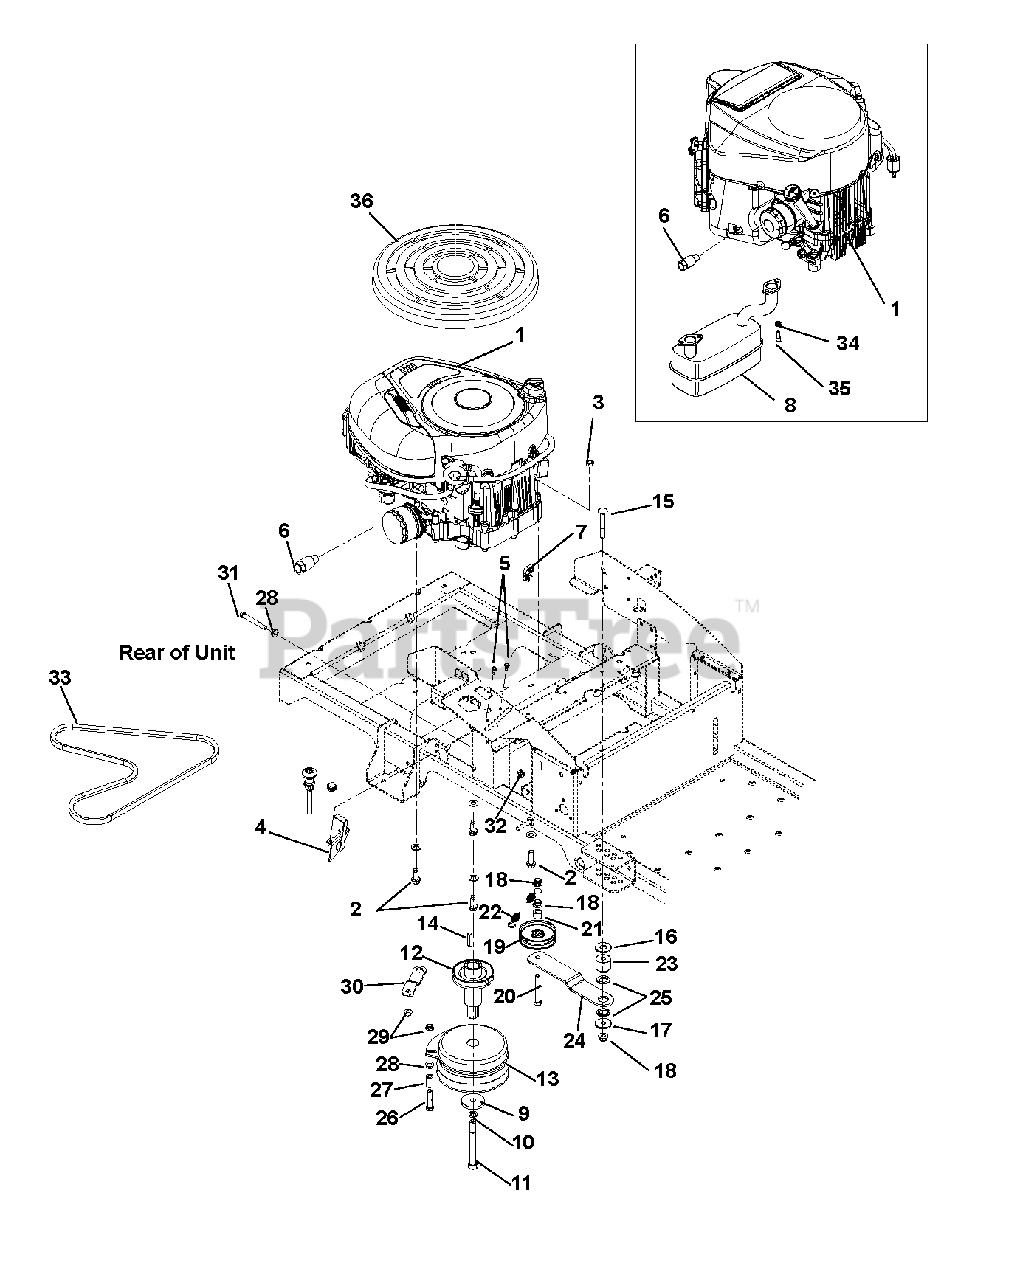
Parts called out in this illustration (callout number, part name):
1	Engine, 16HP V-Twin CE (915327)
2	Screw, Tapping .38-16 x 1.25 Hex Washer Head
3	Nut, Locking Jam .375-16 (915327)
4	Throttle/Choke Cable (915327)
5	Screw, Tapping 10-24 x .50 Hex Washer Head
6	Oil Drain
7	Wire Clip (for .25" hole)
8	Muffler, Twin Briggs
9	Washer, Flat Steel .469 x 2.00 x .25
10	Washer, Locking .44 x .109 Regular
11	Bolt, Hex .44-20 x 4.50 Grade 8
12	Weldment, Crankshaft Extension
13	Clutch, 105 FT*LB MONO Pole
14	Key, Square .25 x 1.25 x .25 SAE 8630 or SAE 1035
15	Bolt, Round Head Square Neck .38-16 x 2.75
16	Washer, Flat Steel .563 x 1.38 x .109
17	Washer, Flat Steel .406 x 1.375 x .135
18	Nut, Locking Nylon Flange .38-16
19	Pulley, Engine Clutch
20	Bolt, Hex .38-16 x 2.75
21	Bushing, Sleeve .391 x .688 x .52
22	Spring, Extension
23	Spacer, Ground Drive Idler
24	Idler Arm, Ground Drive
25	Bushing, Idler Arm
26	Screw, Cap .31-18 x 1.75
27	Spacer, Rubber 5/16 ID x 1.0
28	Nut, Spin Lock Flange .312-18
29	Nut, Locking Top Flange .31-18
30	Bracket, Clutch Stop
31	Bolt, Hex .31-18 x 2.75
32	Nut, Locking Nylon Flange .31-18
33	V-Belt, HA-RAW Edge Laminated
34	Washer, Locking .31 x .078 Regular
35	Capscrew .31-18 x .75 S/HD
36	Guard, Briggs Engine
